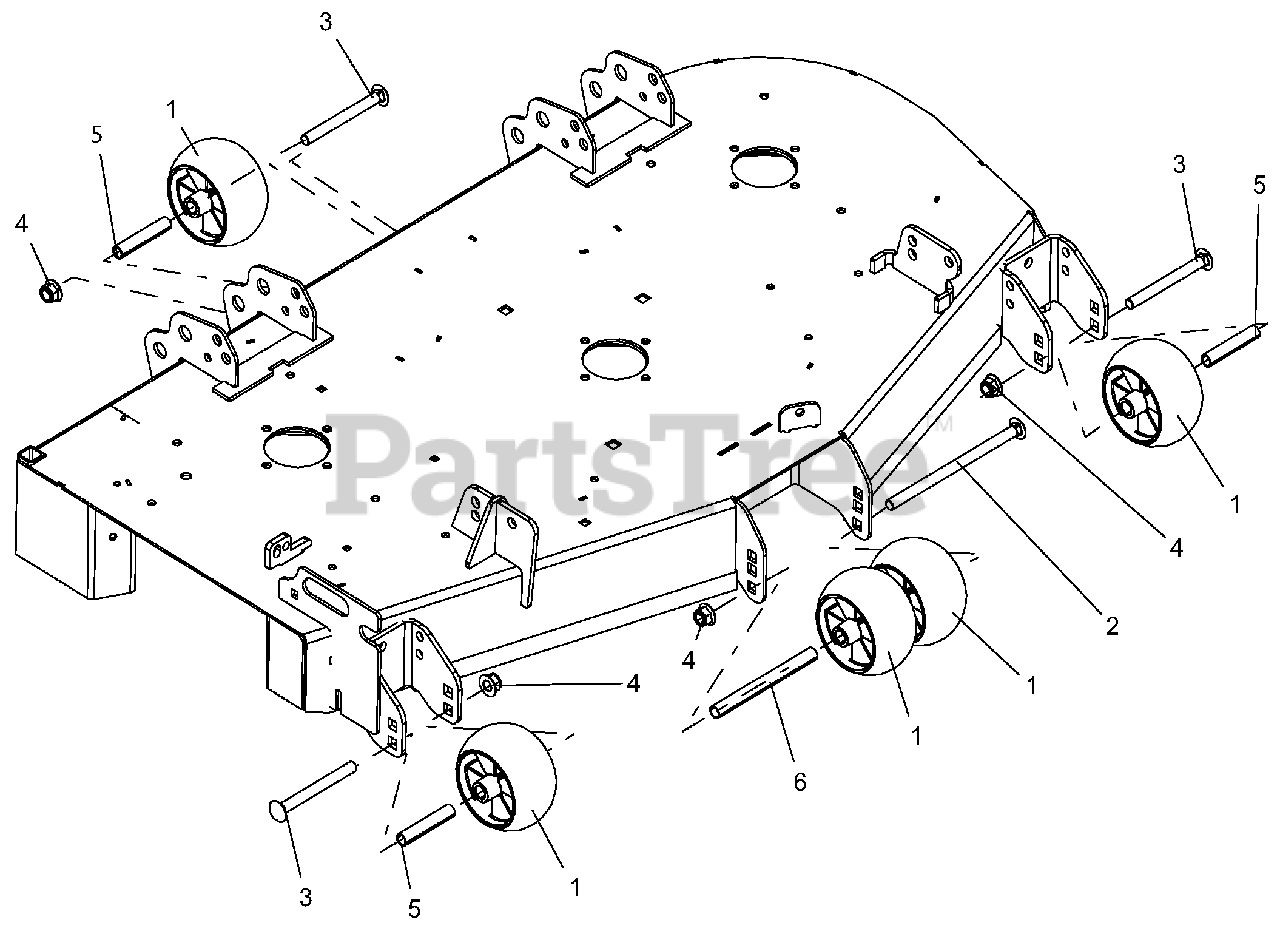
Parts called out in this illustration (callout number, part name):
1	ANTI-SCALP WHEEL - 5X3 CTR
2	BLT-RDHDSQNK .50-13X8.50 Y
3	BLT-RDHDSQNK .50-13X5.00 G5 YWZC
4	NUT-LK-NYL-FLG .50-13 YWZC
5	SPACER, .510X.625X3.35
6	SPACER, .510X.625X6.70
